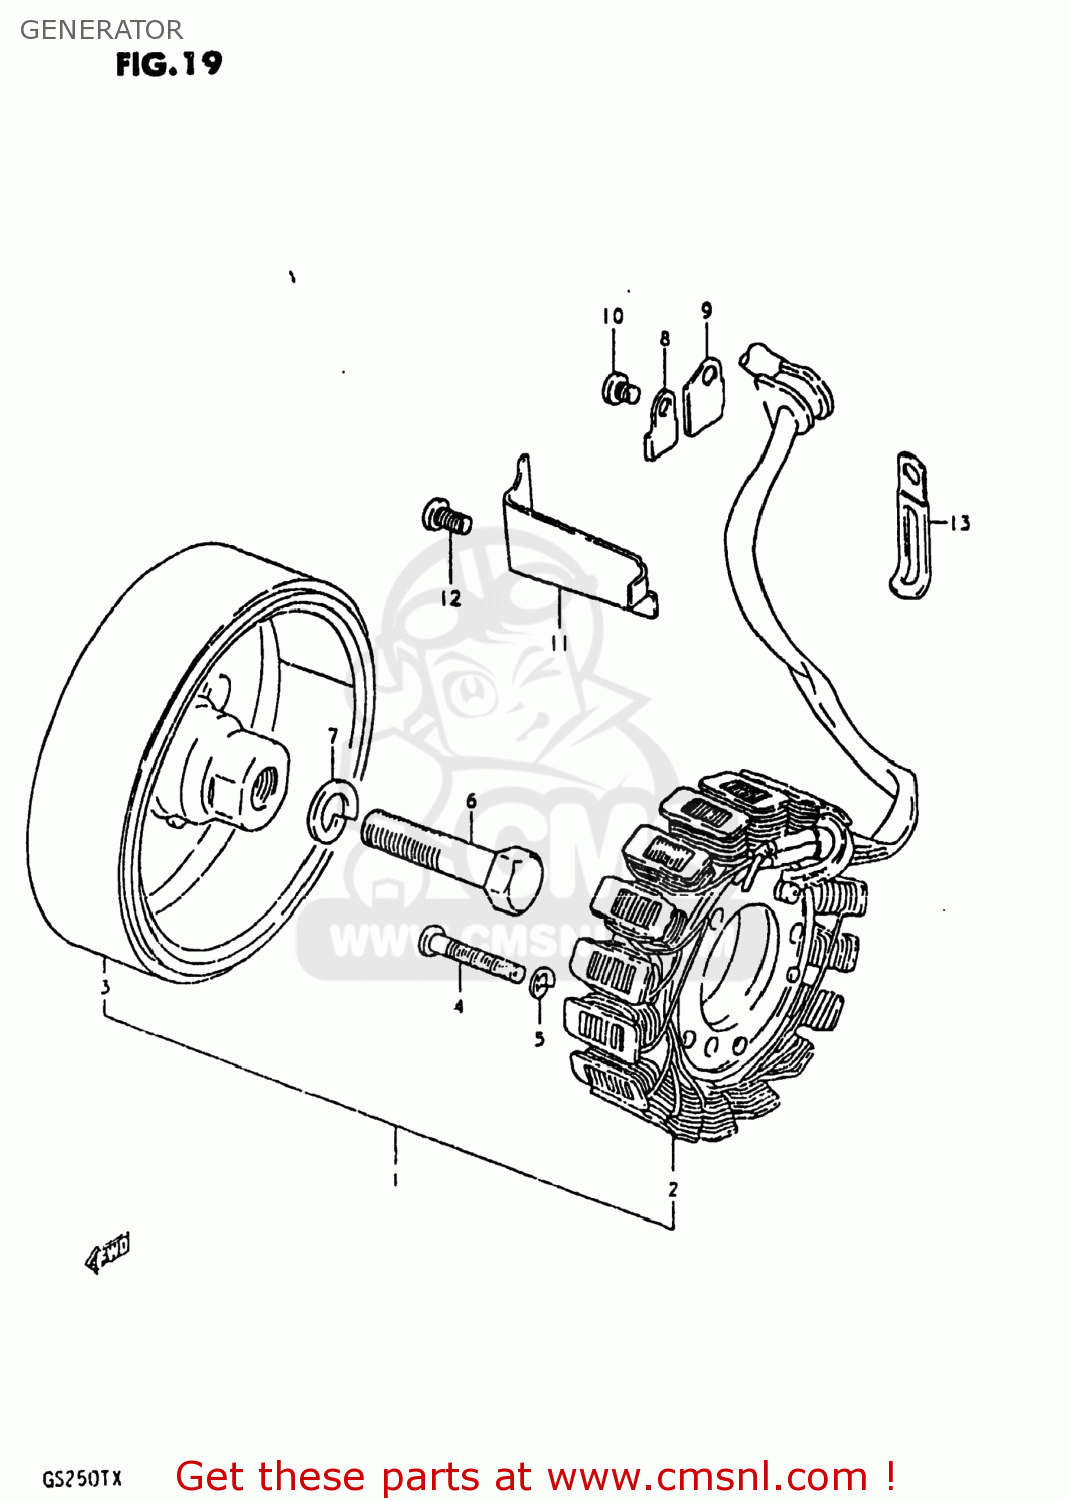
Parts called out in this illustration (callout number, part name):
1	GENERATOR ASSEMBLY
2	STATOR ASSEMBLY
3	ROTOR ASSEMBLY
4	SCREW
5	LOCK WASHER
6	BOLT 12X45
7	WASHER,LOCK 12
8	CLAMP,GENERATOR LEAD WIRE
9	CLAMP,GENERATOR LEAD WIRE
10	SCREW
11	CLAMP,GENERATOR LEAD WIRE
12	SCREW
13	CLAMP L:35
